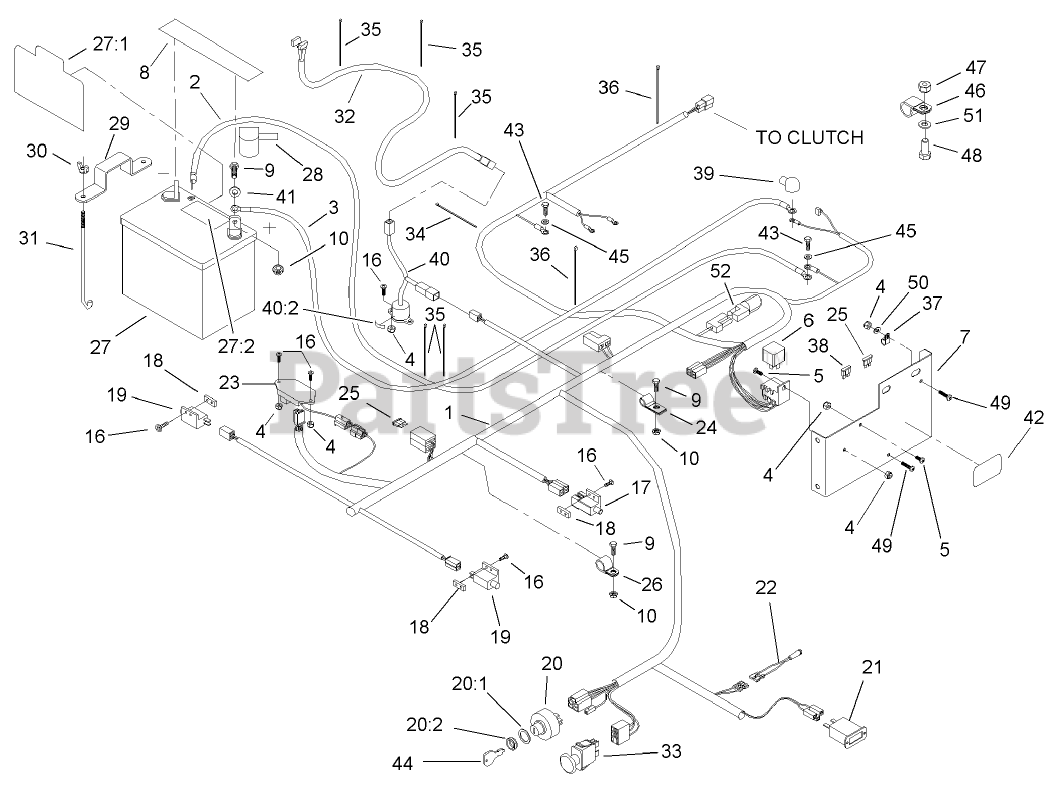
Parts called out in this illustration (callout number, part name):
1	Harness-Wire
2	WIRE-GROUND
3	WIRE-BATTERY, POSITIVE
4	NUT-LOCK, NI
7	PANEL-MOUNT, FUSE
8	Decal-Warning, Battery
9	SCREW-HH
10	NUT-HF
16	SCREW-PPH
17	SWITCH
18	PLATE-TAPPED
19	SWITCH-OPEN, NORMALLY
20	Key Switch ASM
20:1	WASHER-TOOTH, INTERNAL
20:2	NUT-HH
21	METER-HOUR
22	INDICATOR-LED, RED
23	MODULE-DELAY, SEAT
24	CLIP-LOOM
25	FUSE-BLADE TYPE, 20 AMP
27	BATTERY
27:1	Decal-Battery
27:2	Decal-Battery
28	INSULATOR-BATTERY
29	STRAP-HOLDDOWN
30	WINGNUT
31	BOLT-HOLDDOWN
32	HARNESS-WIRING, SEAT
33	SWITCH-DELTA
34	TIE-CABLE
35	TIE-PLASTIC
36	TIE-PLASTIC
37	CLIP-LOOM
38	FUSE-BLADE TYPE, 10 AMP
39	INSULATOR-SOLENOID
40	TILT SWITCH ASM
40:2	DECAL-SWITCH, MERCURY
41	WASHER-FLAT
42	DECAL-RELAY / FUSE
43	SCREW-HH
44	KEY-IGNITION
45	WASHER-PLAIN
46	CLIP-LOOM
47	NUT-LOCK, NI
48	SCREW-HH
49	SCREW-HH
50	WASHER-FLAT
51	WASHER-FLAT
